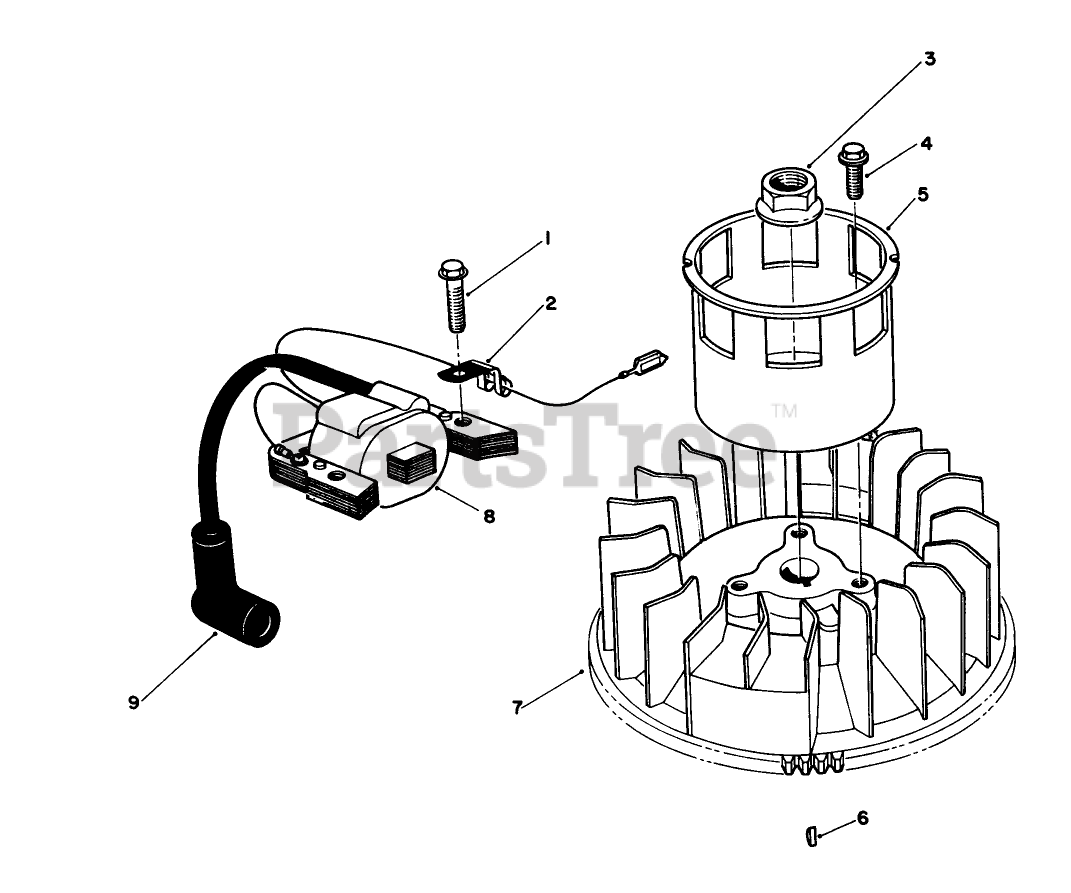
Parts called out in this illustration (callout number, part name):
2	CLAMP
7	FLYWHEEL
8	Coil Assembly-Magneto (Incl. Ref. #9)
9	COVER
